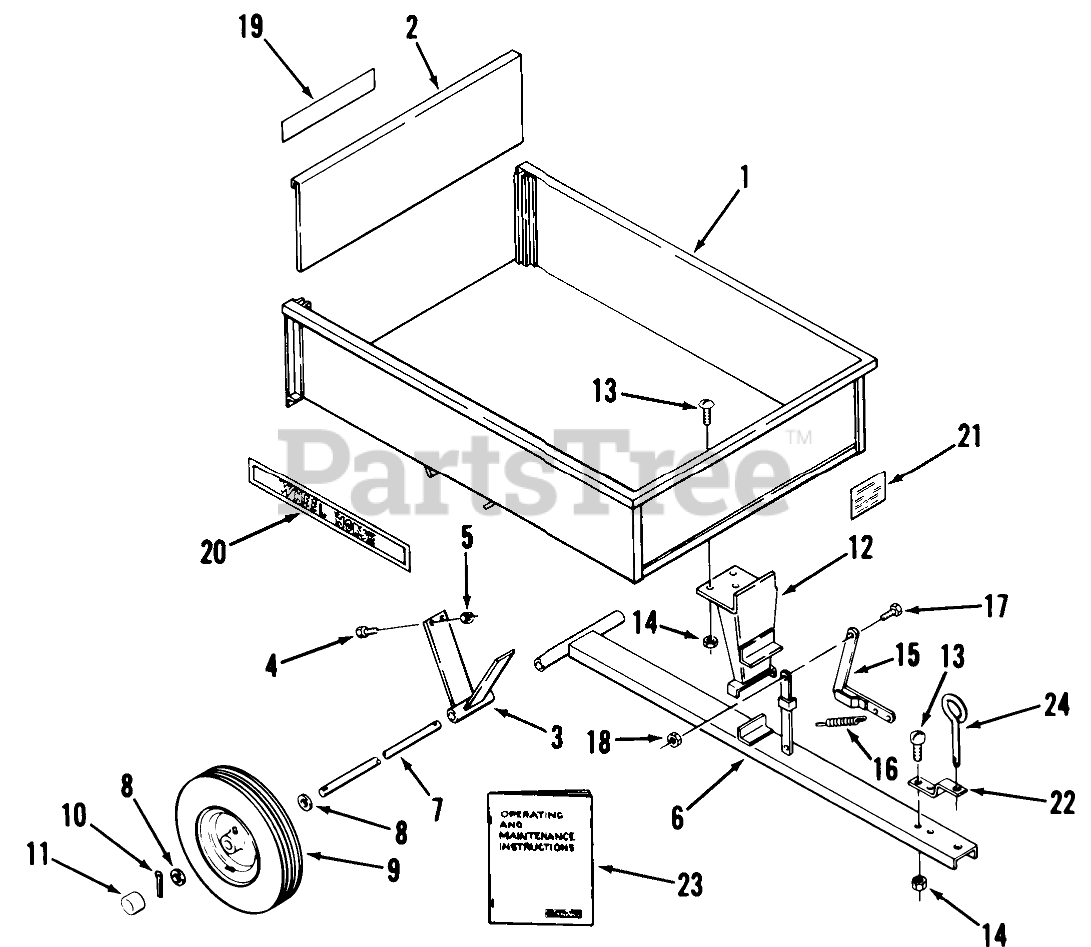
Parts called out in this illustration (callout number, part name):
1	Bed Assembly
2	Rear Gate
3	Axle Holder Assembly
4	BOLT
5	Nut
6	Drawbar Assembly
8	Special Washer
9	Wheel Assembly (4.30-8)
11	HUB CAP
12	Drawbar Spacer Assembly
13	Truss Hd. Bolt 3/8-16 x 3/4
14	Nut
15	Latch Assembly
16	SPRING
17	Bolt
18	Nut
19	DECAL-WHEEL HORSE
20	Decal
21	Decal-Weight Limit
22	Clevis
23	Operating and Maintenance Instructions
24	PIN-TOOL
